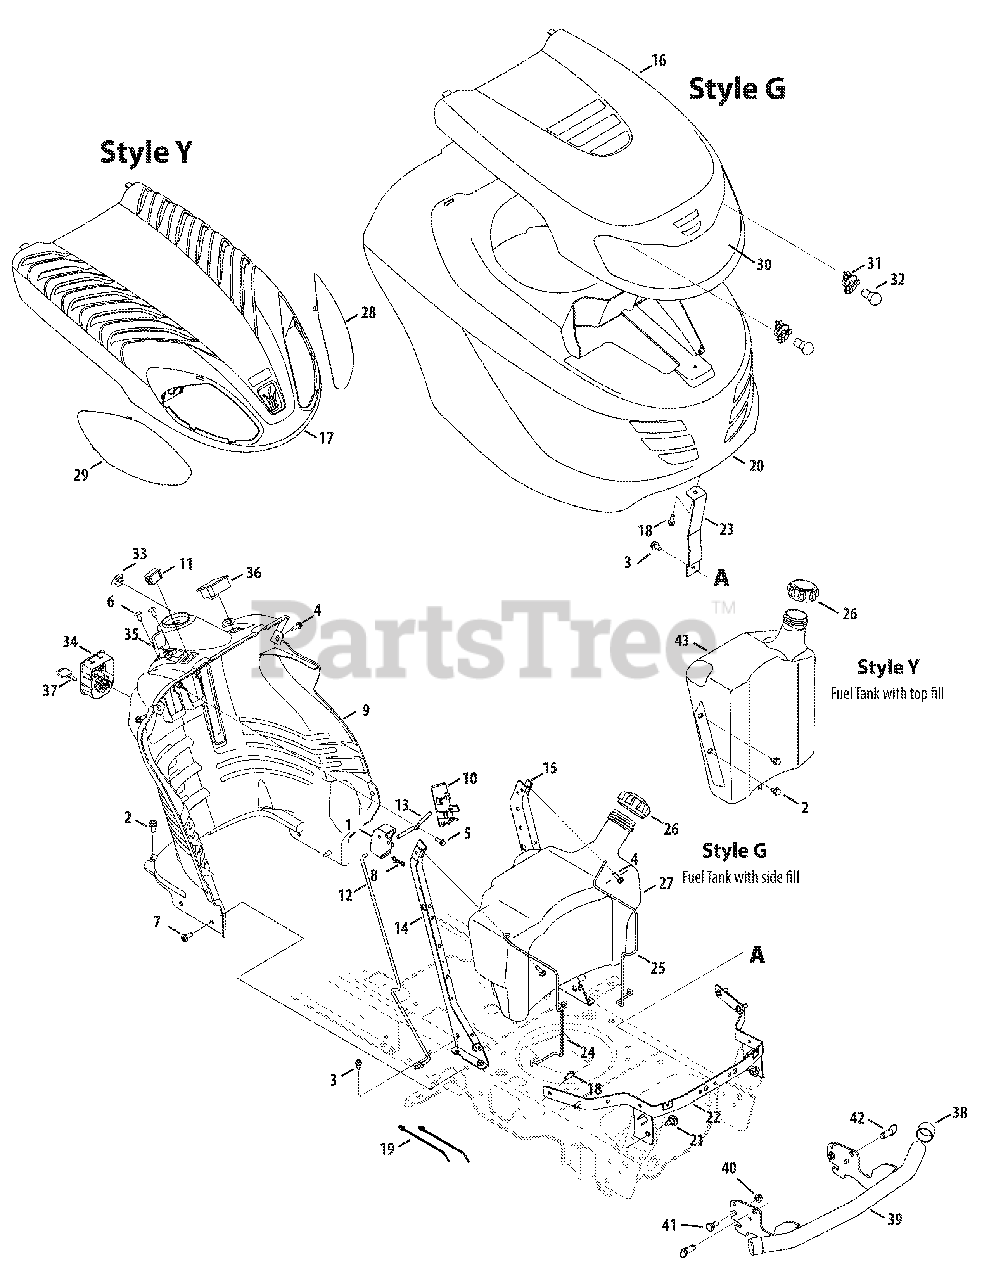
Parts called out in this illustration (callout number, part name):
1	Dash Lever
2	S-Tapp Scr 5/16-18 x .75
3	Hex Wash S-Tapp Scr 1/4-20 x .50
4	Hex TT Screw 1/4-20 x .75
5	Hex Tapp Scr 1/4 x .75" Lg.
6	Torx Mach. AB-Tapp Scr. 1/4-14 x .625 Lg
7	Screw 5/16-18 x .75
8	Bow-Tie Cotter Pin
9	Dash Panel (Man. PTO w/fuel level window)
10	Cruise Cover Y/G Style
11	Light Switch Cap
12	Latch Control Rod
13	Pivot Rod
14	RH Dash Support Plate
15	LH Dash Support Plate
16	Upper "G" Style Hood
17	Upper "Y" Style Hood
18	Screw, Bos, 1/4 Dia. x .75
19	Cable Tie
20	G Style Hood (w/side fill fuel tank)
21	Shoulder Screw .43 x .29, 5/16-18
22	Hood Pivot Bracket
23	Hood Support Bracket
24	Tank Support Rod RH
25	Tank Support Rod LH
26	Cap-Fuel
27	Fuel Tank 2.75 Gal. (side fill)
28	Lens LH - Style "Y"
29	Lens RH - Style "Y"
30	Lens (Style G)
30	Reflector Label
31	Socket
32	Miniature Lamp 12V Socket Type
33	Choke Plug
34	Key Switch Module
35	Throttle/Choke Cont. Cable 25" Lg.
36	Am Meter
37	Ignition Key w/Plastic Cover
38	Bumper Cap
39	Bumper Assembly
40	Hex Lock-Nut 3/8-16 Gr.B
41	Shoulder Scr. .498 x .340: 3/8-16
42	Quick Pin 1/2" dia. x 0.50
43	Fuel Tank
